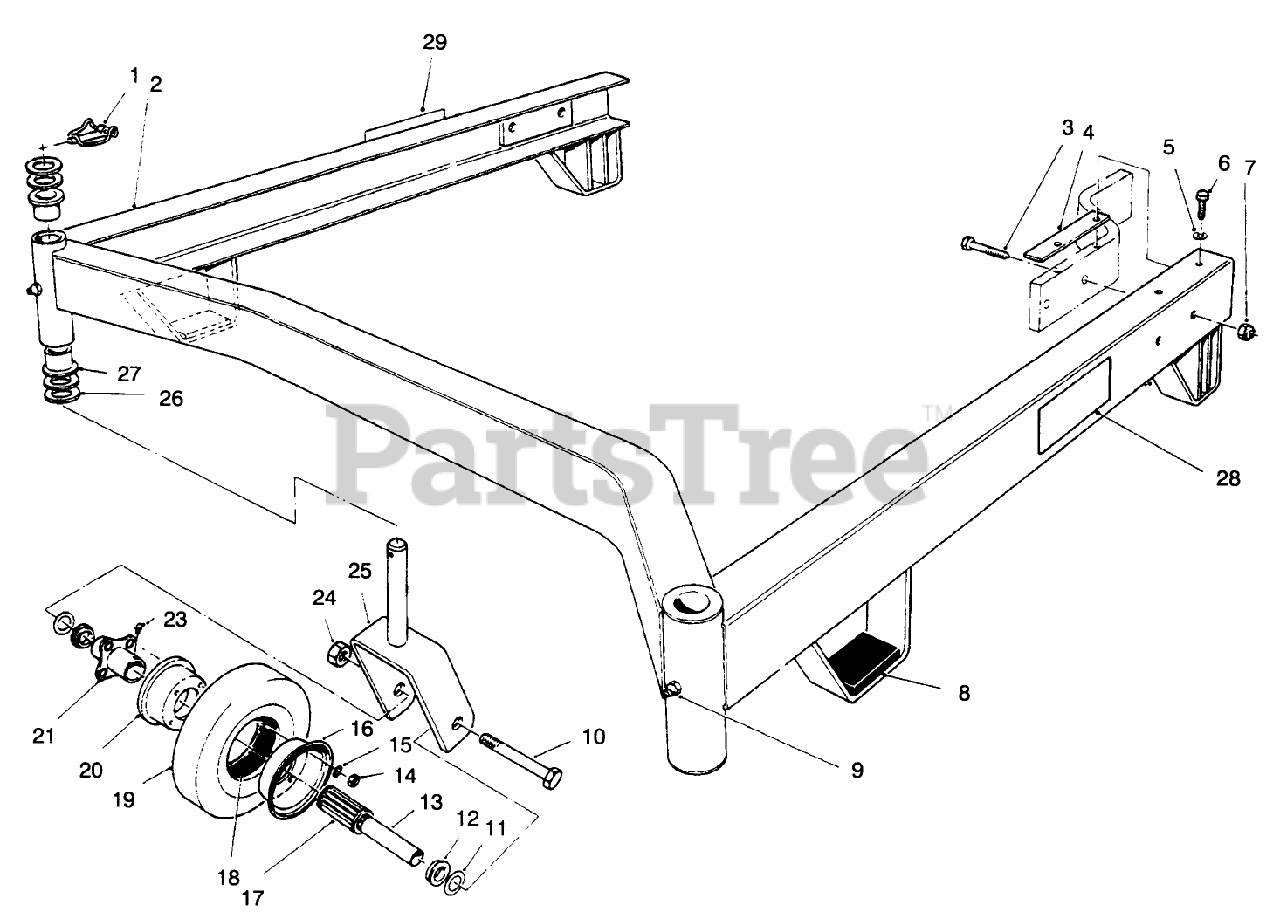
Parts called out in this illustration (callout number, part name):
1	PIN-LYNCH
2	Suspension Assembly-52" (Incl. Ref. #9, & 27)
3	SCREW-HH
4	SHIM-CARRIER
5	WASHER-FLAT
6	SCREW-HHF
7	NUT-LOCK, SIDE
8	CUSHION-RUBBER
9	FITTING-GREASE
10	SCREW-HH
11	WASHER-FLAT
12	BEARING-OUTSIDE
13	SPANNER-TIRE
14	NUT-HEX
15	WASHER-LOCK
16	MALE WHEEL HALF
17	BEARING-ROLLER
18	TUBE-INNER (W/VALVE)
20	FEMALE WHEEL HALF
21	HUB-CENTER
23	FITTING-LUBE, 45 DEG
24	NUT-HEX
25	Castor Fork
26	WASHER-THRUST
27	Bushing
28	DECAL-HOC, RH
29	DECAL-HOC, LH
